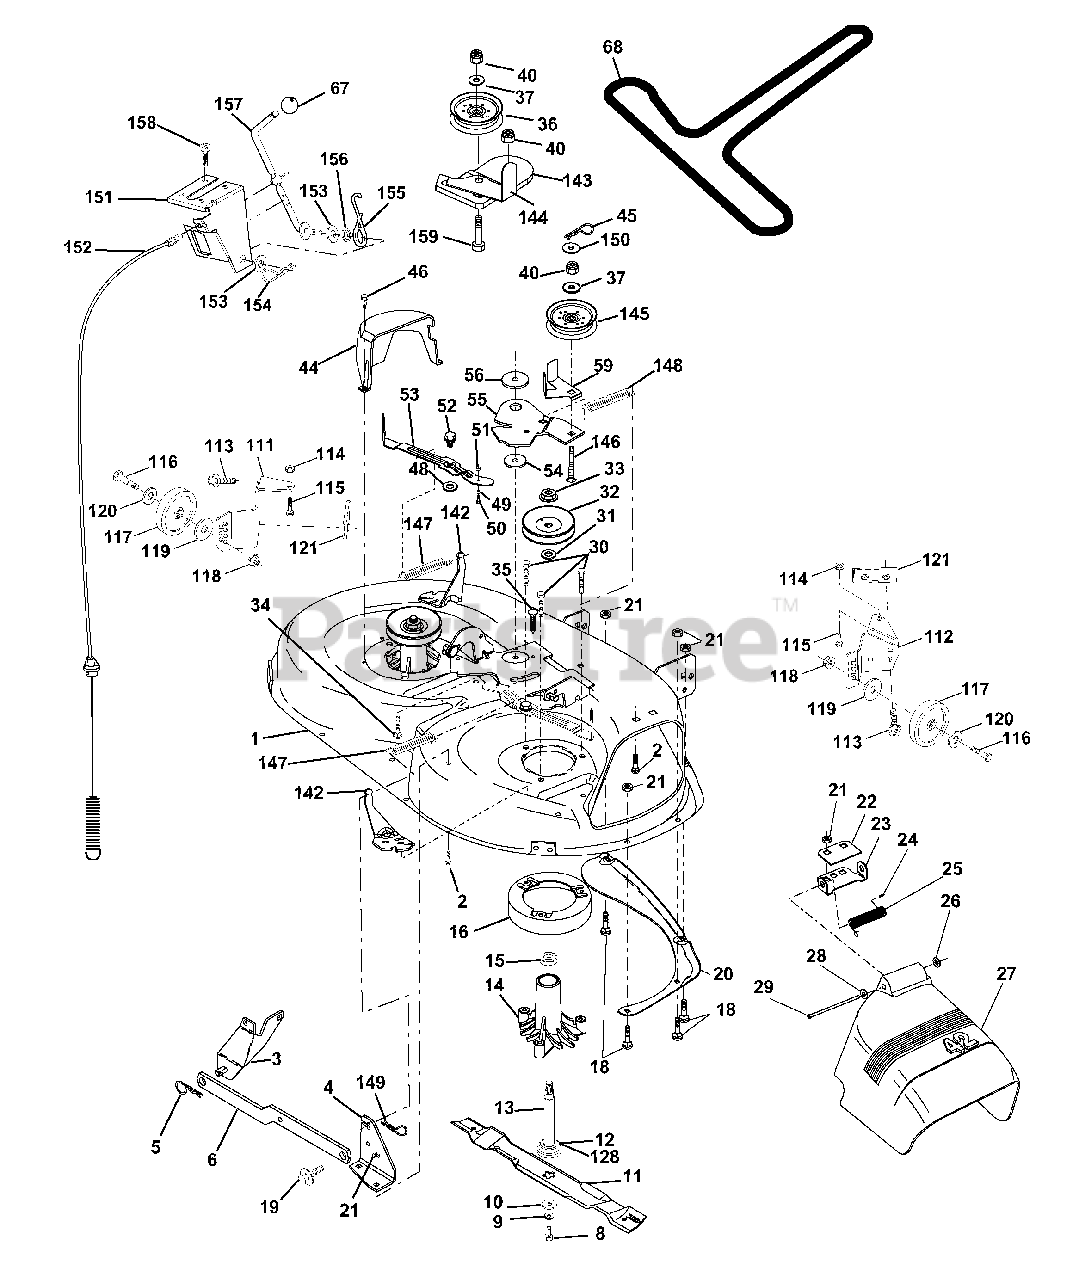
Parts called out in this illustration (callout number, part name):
1	Mower Deck Assembly, 42"
2	Bolt
3	Bracket Asm Fr. Sway Bar 3/42
4	Bracket Asm Deck 42" Sway Bar
5	Retainer Spring
6	Arm, Suspension, Rear
8	Bolt 3/8-24 x 25 Grade 8 patched
9	Washer, Lock
10	Washer, Hardened
11	Blade
12	Bearing, Ball #6204
13	Shaft Assembly, Mandrel, Vented
14	Housing, Mandrel, Vented
15	Bearing, Ball, Mandrel
16	Stripper, Vented Mower Deck
18	Bolt, Carriage 5/16-18 x 5/8
19	Bolt, Shoulder
20	Baffle, Vortex
21	Nut
22	Stiffener Bracket
23	Bracket, Deflector Mower 42"
24	Cap, Sleeve 80 x 112 Blk Mower
25	Spring, Torsion, Deflector 2 52
26	Nut, Push Phos & Oil
27	Shield, Deflector 42" Blk
28	Washer 11/32 x 5/8 x 16 Gauge
29	Rod, Hinge 42" 6 75 W/G
30	Screw Thdrol Washer Head
31	Washer, Spacer Mower Vented
32	Pulley, Mandrel
33	Nut, Toplock 9/16
34	Bolt
35	Fastener, Christmas Tree
36	Pulley, Idler, Flat
37	Washer 13/32 x 13/16 x 16 Gauge
40	Nut
44	Guard, Mandrel, LH
45	Retainer
46	Screw, Thdrol 1/4-20 x 5/8 T
48	Washer,Hardened
49	Roller Assembly, Cam Follower
50	Bolt, Shoulder #10-24 Grade 5
51	Locknut
52	Bolt, Shoulder 5/16-18 UNC
53	Arm Assembly, Pad, Brake
54	Washer,Hardened
55	Arm, Idler
56	Spacer, Retainer
59	Guard TUV Idler
67	Knob
68	V-Belt, 42" Mower
111	Bracket, Gauge, Wheel LH
112	Bracket, Gauge, Wheel RH
113	Screw 5/16 - 18 x 3/4
114	Nut, Keps 5/16 - 18 UNC
115	Bolt, Carriage 5/16-18 x 1/2
116	Bolt, Shoulder
117	Wheel, Gauge
118	Nut Centerlock 3/8-16
119	Washer 3/8 x 7/8 x 14 Ga.
120	Washer 17/32 x 15/16 x 12 Ga.
121	Bracket, Extruded
128	Washer, Felt
142	Arm Spring Brake Mower
143	Bracket Arm Idler 42"
144	Keeper Belt 42" Clutch Cable
145	Pulley Idler Flat
146	Bolt Carriage Idler
147	Spring Extension
148	Spring Return Idler
149	Retainer Spring Yellow
150	Washer 9/32 x 3/4 x 16 Ga.
151	Bracket Clutch Cable
152	Clutch Cable 42"
153	Washer Flat 3/8" Type B
154	Spring Retainer
155	Spring Retention LVR CLTCH CAB
156	Spacer Clutch Cable
157	Rod Clutch Cable 3/8"
158	Screw Hex Thd Cut 1/4-20 x 5/8
159	Bolt Rdhd Sqn 3/8-16 UNC x 1-3/4
